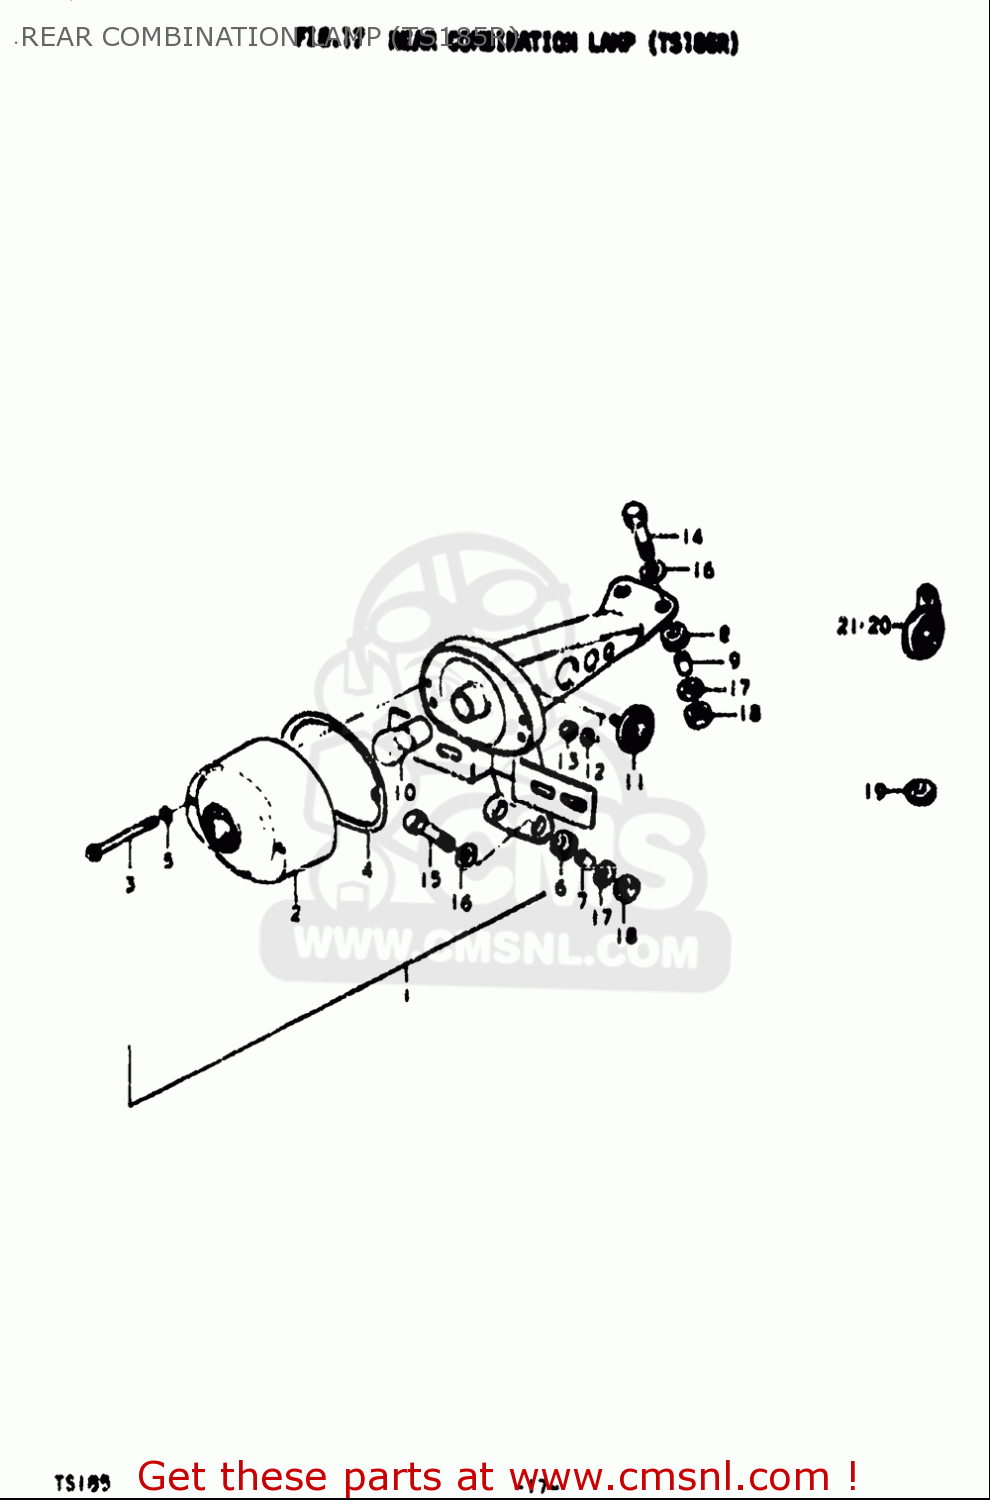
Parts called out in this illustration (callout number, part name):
2	LENS,RR COMBINATION LAMP
6	CUSHION
7	SPACER
8	CUSHION
10	BULB(6V17/5.3W,STANLEY,A4813)
12	WASHER,LOCK
13	NUT
14	BOLT
15	BOLT
16	WASHER(6.5X20X1.6)
17	WASHER,LOCK
18	NUT
